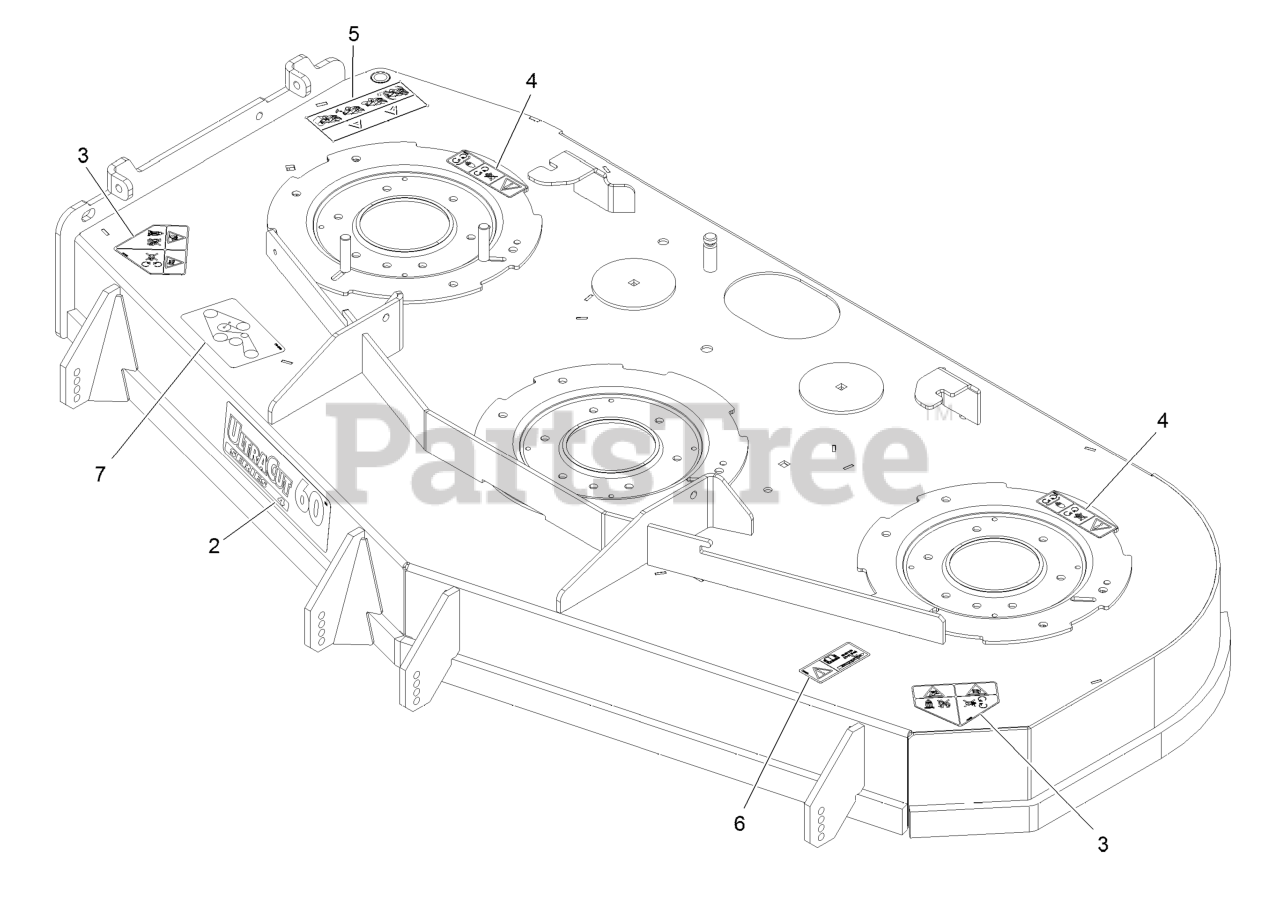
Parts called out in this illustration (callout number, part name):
2	DECAL,ULTRACUT 60 SERIES
3	DECAL-DANGER
4	DECAL-WARNING, BAGGER
5	DECAL-BOLT TORQUE
6	DECAL-COVER, MISSING
7	DECAL-BELT ROUTING
